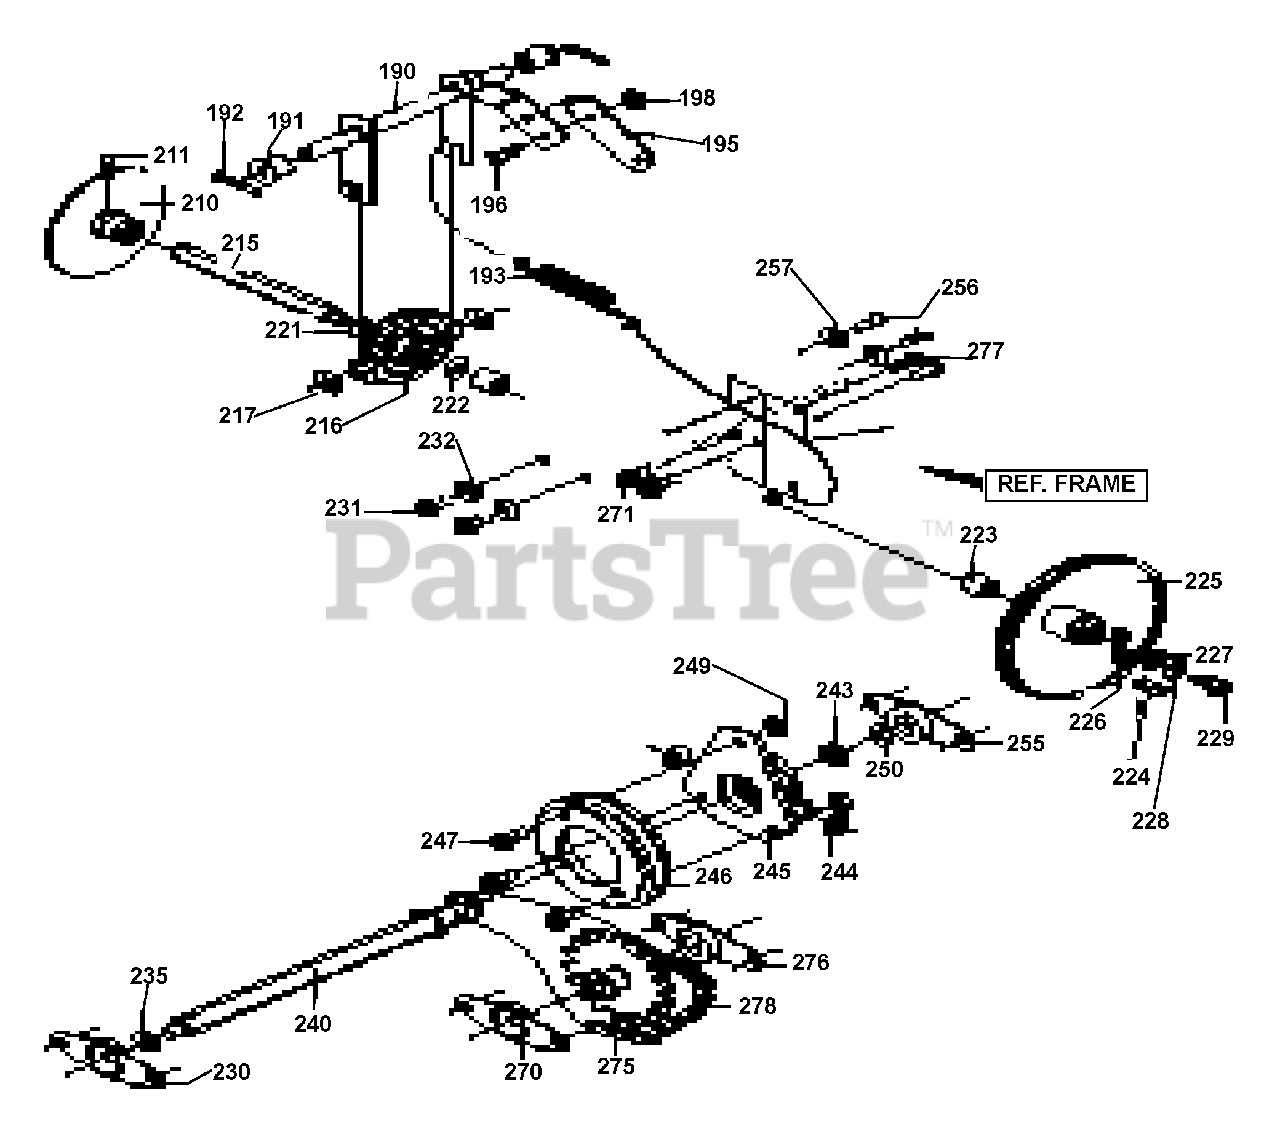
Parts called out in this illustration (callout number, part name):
190	LEVER, ASSY TRACTION
191	BEARING, FLANGE
192	PIN, COTTER.125DIAX1.00LG
193	SPRING, RETURN
195	LEVER, SPRING
196	SCREW, 1/4-20X .63 HHCFT
198	NUT, 1/4-20 REGHEXCTRLK
210	DISC, ASSY FRICWHL
211	ZERK, GREASE.25 28X1.12LG
215	SHAFT, HEX TRACTION
216	BEARING, TRUNION 1.25 ID
217	WASHER, FLAT.53 X1.00X.063
221	RING, RETEX
222	FLATWASHER.680X1.12X.060
223	BEARING, BALL
224	KEY, SQUARE .18SQX.63LG
225	PULLEY, V3L 6.50X .56
226	WASHER, WAVE
227	WASHER, FLAT .281X1.00X.063
228	WASHER, 263X.49X.07
229	SCREW, 1/4-20X .75 HHC
230	BEARING & RETAINER, ASSY
231	SCREW, 5/16-18X .50
232	WASHER, .328X.60X.09
235	WASHER, SP .502X .75X.0605
240	HEX, ASSY#40-8TW/PBRG
243	RING, RETEX
244	WASHER, FLAT.53 X1.00X.063
245	BEARING, TRUNION
246	WHEEL, ASSYFRICTION DISC
247	SCREW, 1/4-20X .63 HHCFT
249	NUT, 1/4-20 HEX KEPS
250	WASHER, SP .502X 75X.0605
255	BEARING & RETAINER, ASSY
256	SCREW, 5/16-18X .50
257	WASHER, .328X.60X.09\
270	BEARING & RETAINER, ASSY
271	SCREW, 5/16-18X .50
275	JACK, ASSY#41-36T&7T
